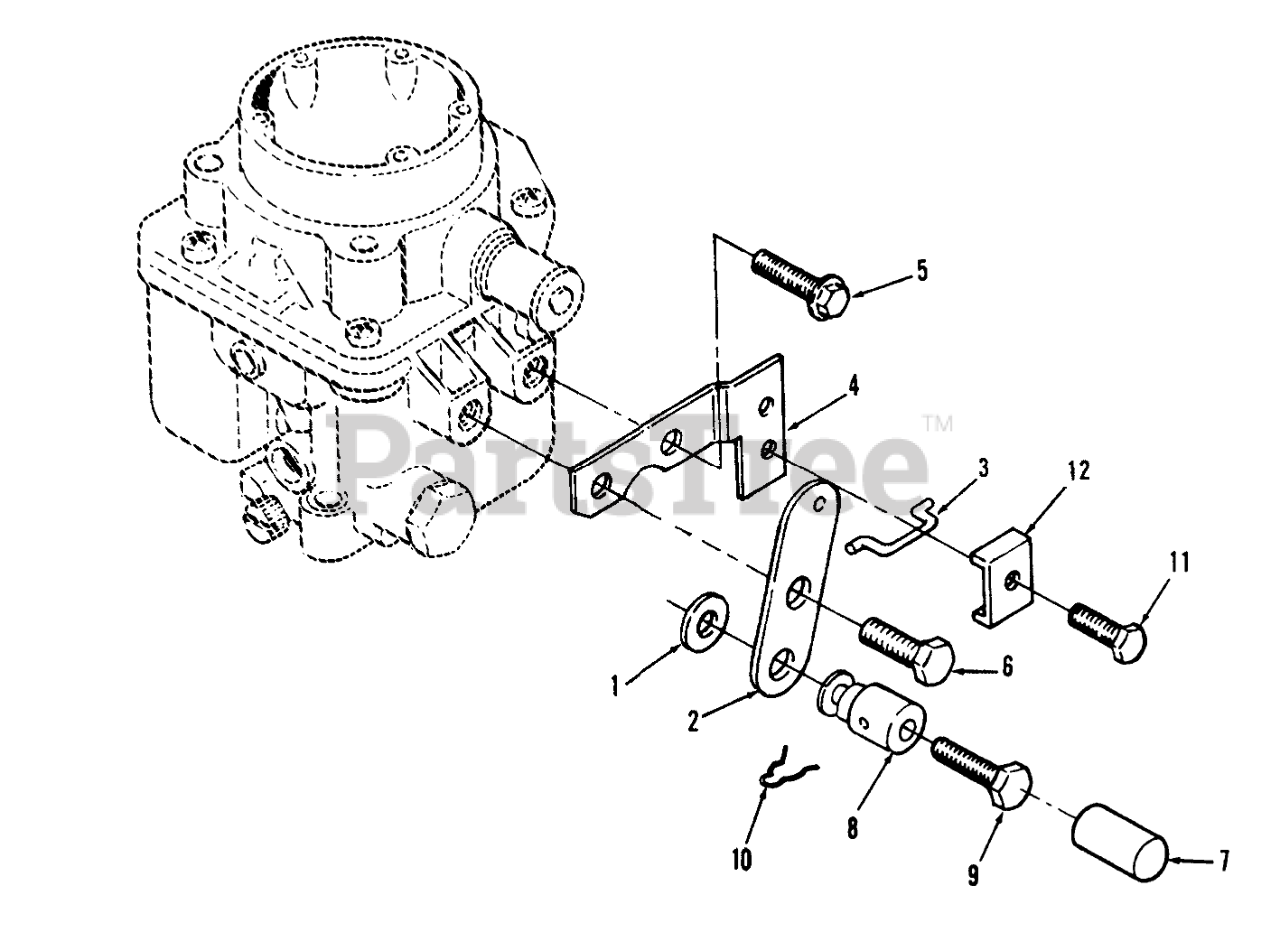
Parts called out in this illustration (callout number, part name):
1	Washer
2	SWIVEL-CHOKE
3	LINK-CHOKE
4	BRACKET
5	SCREW-HWH
6	MACHINE SCREW
8	SWIVEL
9	SCREW
10	PIN-COTTER
11	SCREW-TAPPING
